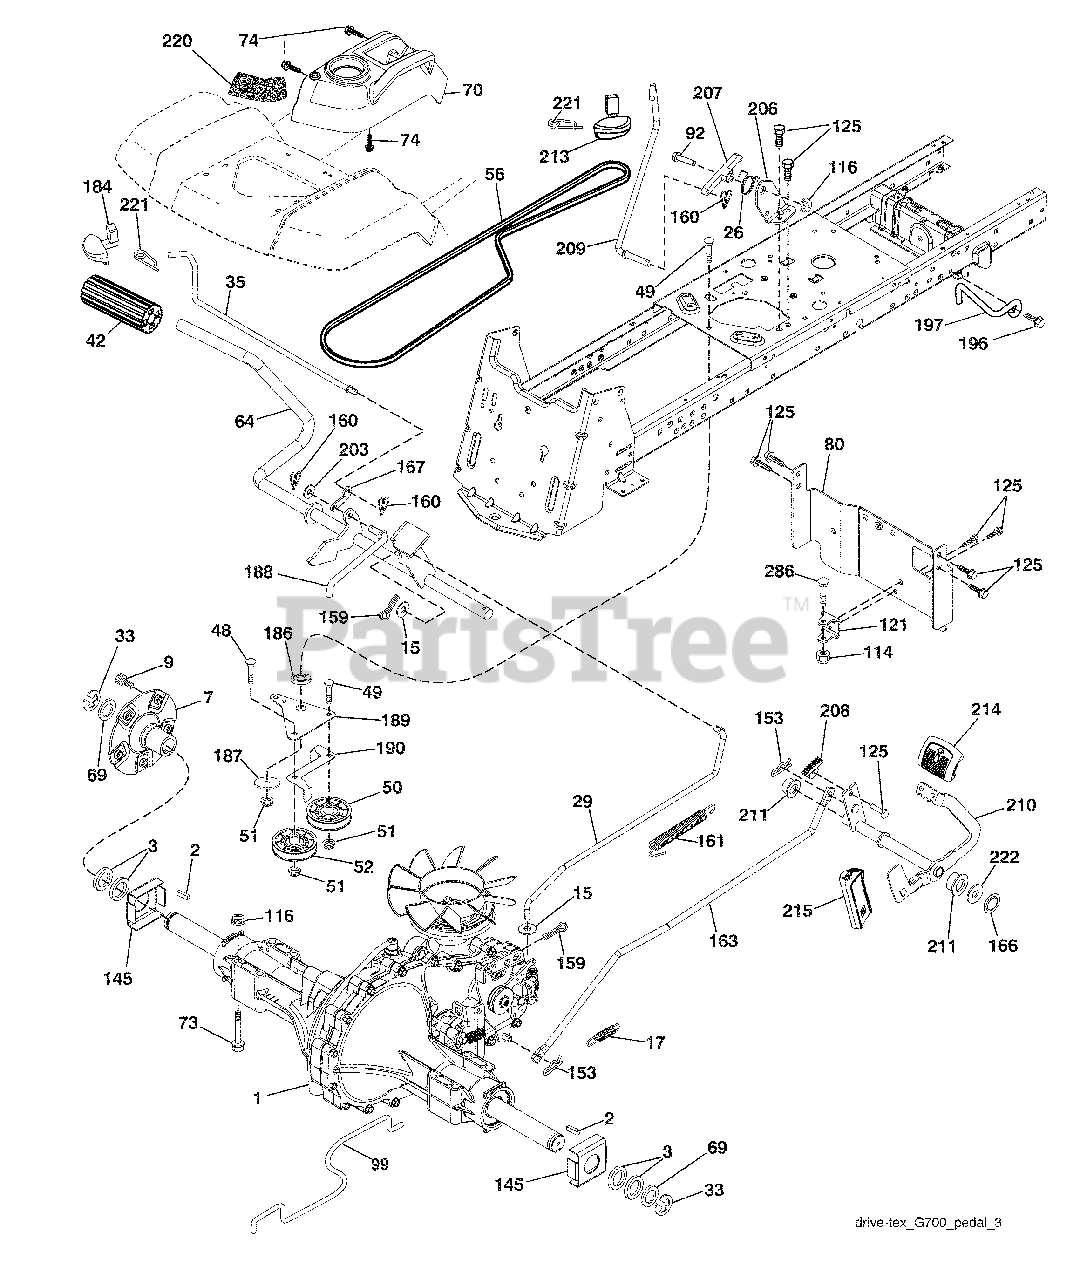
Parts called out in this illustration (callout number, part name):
2	Key 1/4 x 2.5
3	Washer Thrust Axle Hardened
7	Hub Asm. Wheel
9	Bolt Hub Wheel
15	Washer 13/32 x 13/16 x 16 Ga.
17	Spring, Brake
26	Spring Return Cruise
29	Rod, Brake
35	Rod, Brake, Park
42	Cover, Foot Pedal
48	Bolt Carr Sh 3/8-16 x 1-1/2 Gr.5
50	Pulley Idler Flat
51	Lock Nut 3/8-16
52	Idler V-Groove 910" Offset
56	V-Belt, Drive
64	Shaft Asm. Pedal Brake Control
69	Washer 1-1/32 x 1-5/8 x 16 Ga.
70	Console Asm
73	Bolt Hex 5/16-18 x 3 Gr. 5
74	Screw 1/4 x 1/2
80	Strap Torque
92	Bolt 5/16-18 x 1/2
99	Spring Bypass
114	Nut Lock Hex W/Ins. 5/16-18 unc
116	Nut Lock Hex Flange 5/16-18
121	Bracket Strap Torque
125	Screw 5/16-18 x 3/4
145	Washer Axle Flange
153	Retainer Spring
159	Pin Cotter 1/8 x 3/4
160	Retainer Clip
161	Spring, Return, Clutch
163	Rod Pedal Control
166	Nut Push .625
167	Latch Brake Parking
184	Handle Parking Brake
186	Spacer Retainer
187	Washer
188	Link Clutch Ground Drive
189	Bellcrank Ground Drive
190	Keeper Bellcrank Ground Drive
196	Screw 3/8-16 x 1
197	Bracket Clutch Anti-Rotation
203	Washer 11/32 x 11/16 x 16 Ga.
206	Bracket Mount Latch Cruise
207	Latch Control Cruise
208	Gear Sector Control Cruise
209	Rod Control Cruise
210	Rocker Asm. Pedal Control
211	Bearing Nylon
213	Knob Control Cruise
214	Pedal Forward
215	Pedal Reverse
220	Reflector RH
221	Retainer Spring Clip Handle
222	Washer 21/32 x 1-1/4 x 10 Ga.
286	Bolt 5/16-18 x 2.75
